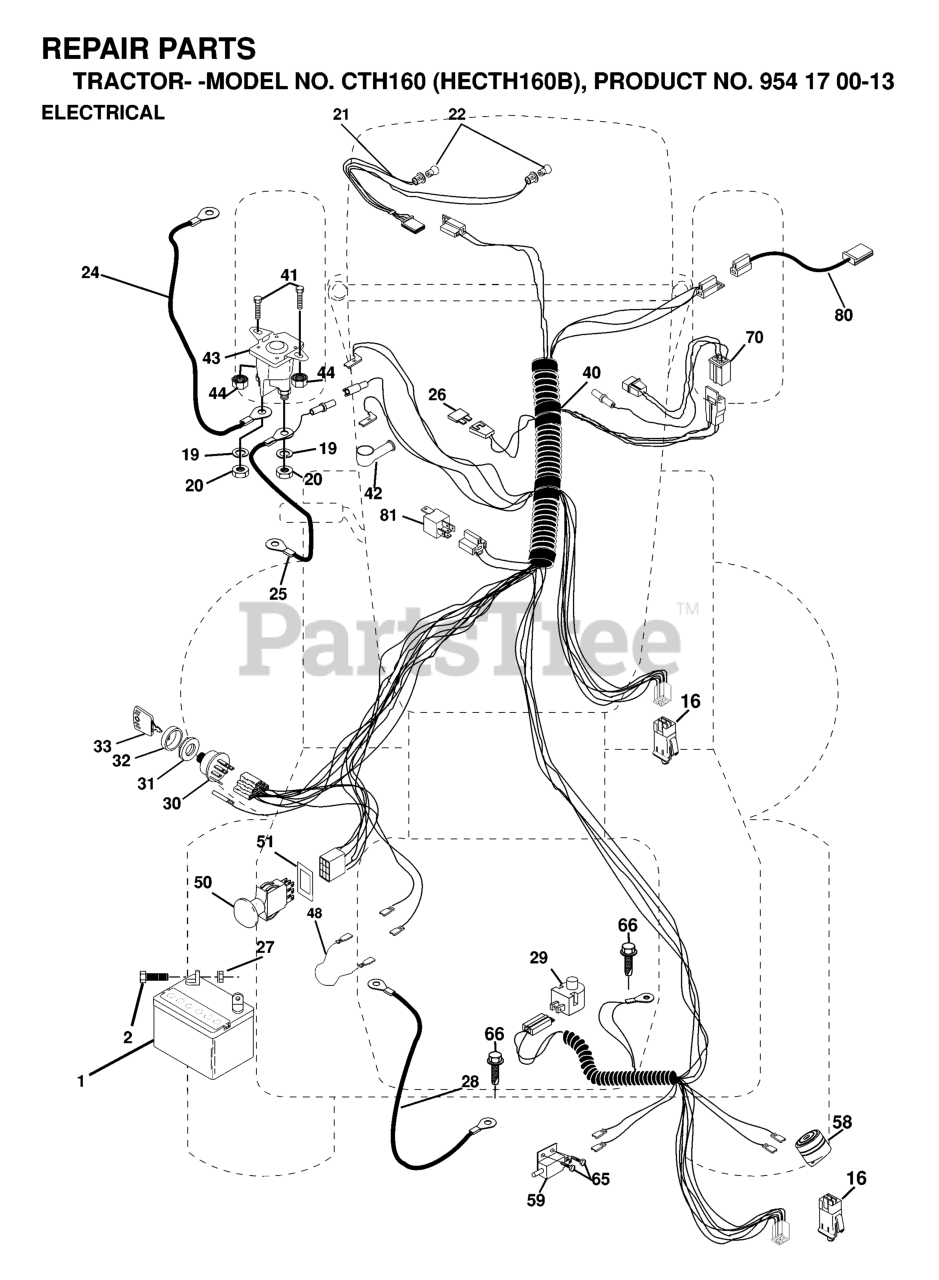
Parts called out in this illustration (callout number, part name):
1	BATTERY 12 VOLT 25 AMP
2	BOLT.HEX.1/4.X.3/4.DICHROMATE
16	SWITCH INTERLOCK
19	LOCKWASHER
20	NUT
24	BATTERY CABLE GT
25	CABLE BATTERY
26	FUSE 15 AMP
27	NUT
28	CABLE GROUND
29	PLUNGER SWITCH (COLOR:OLIVE)
30	SWITCH.IGNITION.4.POSITION
31	NUT IGNITION
32	COVER SWITCH KEY
33	KEY.MOLDED.GENERIC
40	CABLE ASS[
41	BOLT
42	TERMINAL COVER
43	SOLINOID
44	Nut, Keps Blk Hex 1/4-20 UNC
48	ADAPTER.AMMETER
50	SWITCH PTO 3 PDT
51	FRAME RETAINING RING
58	REPL BY 532 16 59-93
65	Screw, Hex Wsh. Tap #10-16 x 1/2
70	CABLE ASS[
80	HARNESS, CLUTCH
81	RELAY.ASSY.T
